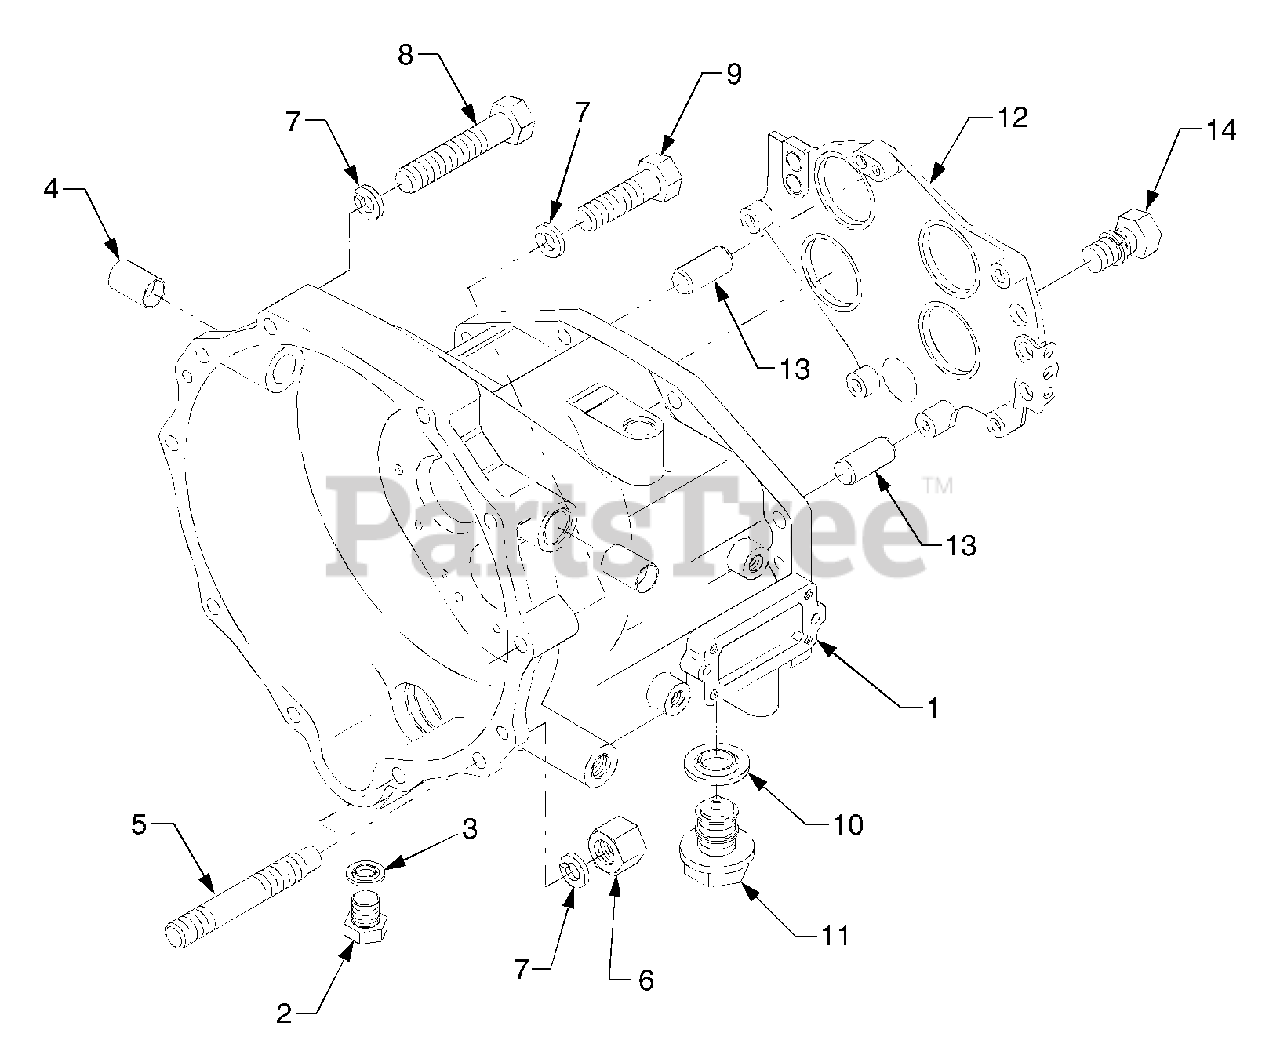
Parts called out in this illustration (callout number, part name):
1	Housing, Clutch
7	Washer, Spring
11	Plug, Drain
12	Cover, Bearing
13	Pin, Straight
